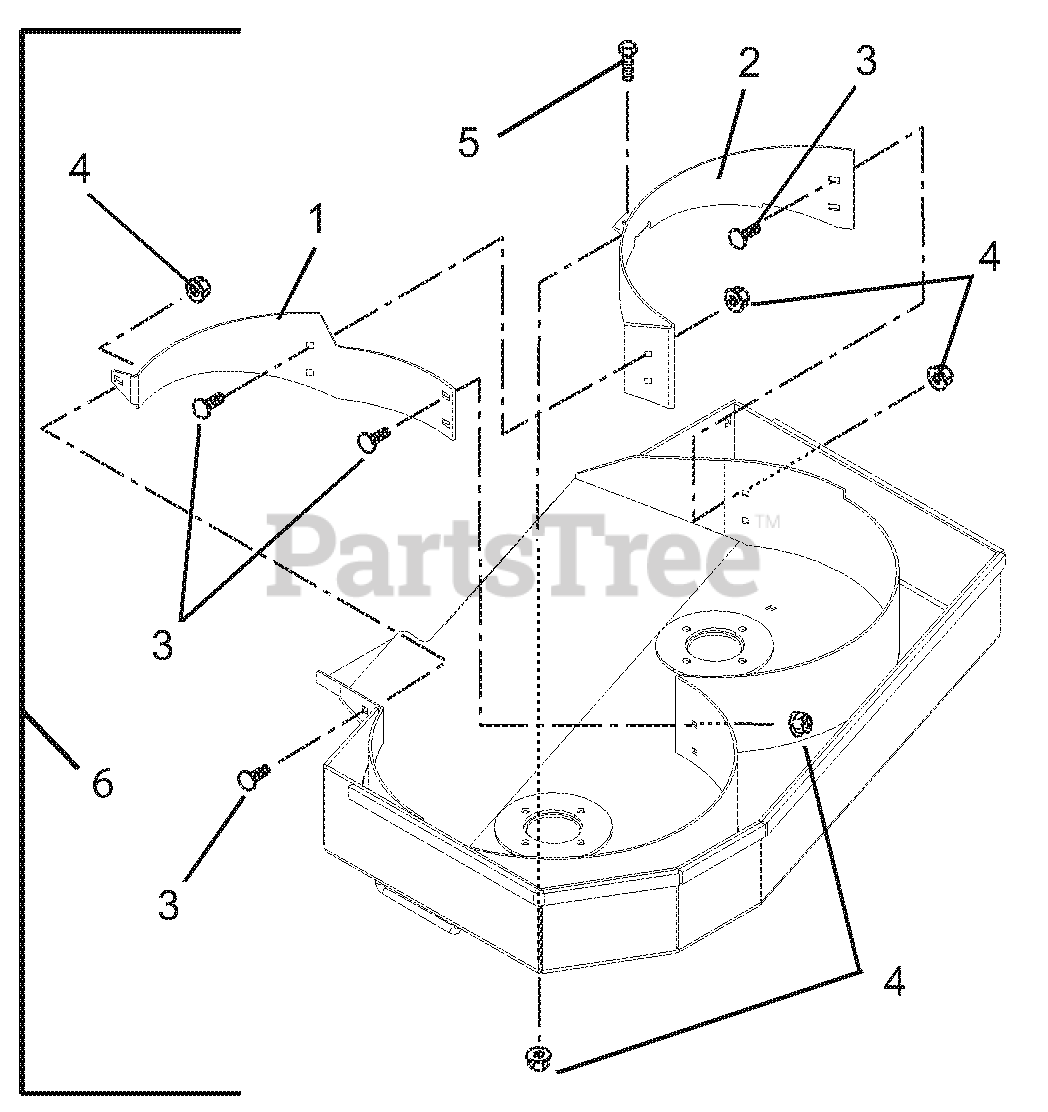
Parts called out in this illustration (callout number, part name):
1	BAFFLE-MULCH-LEFT REAR-34" RD
2	BAFFLE-MULCH-RIGHT REAR-34" RD
3	@BLT-RDHDSQNK .31-18X.75 G5YZ
4	@NUT-LK-TOP-FLG .31-18 YWZC
5	@BLT-HEX .31-18X.75 GR5 YWZC
6	KIT-34" MULCH-REAR DISCHARGE
